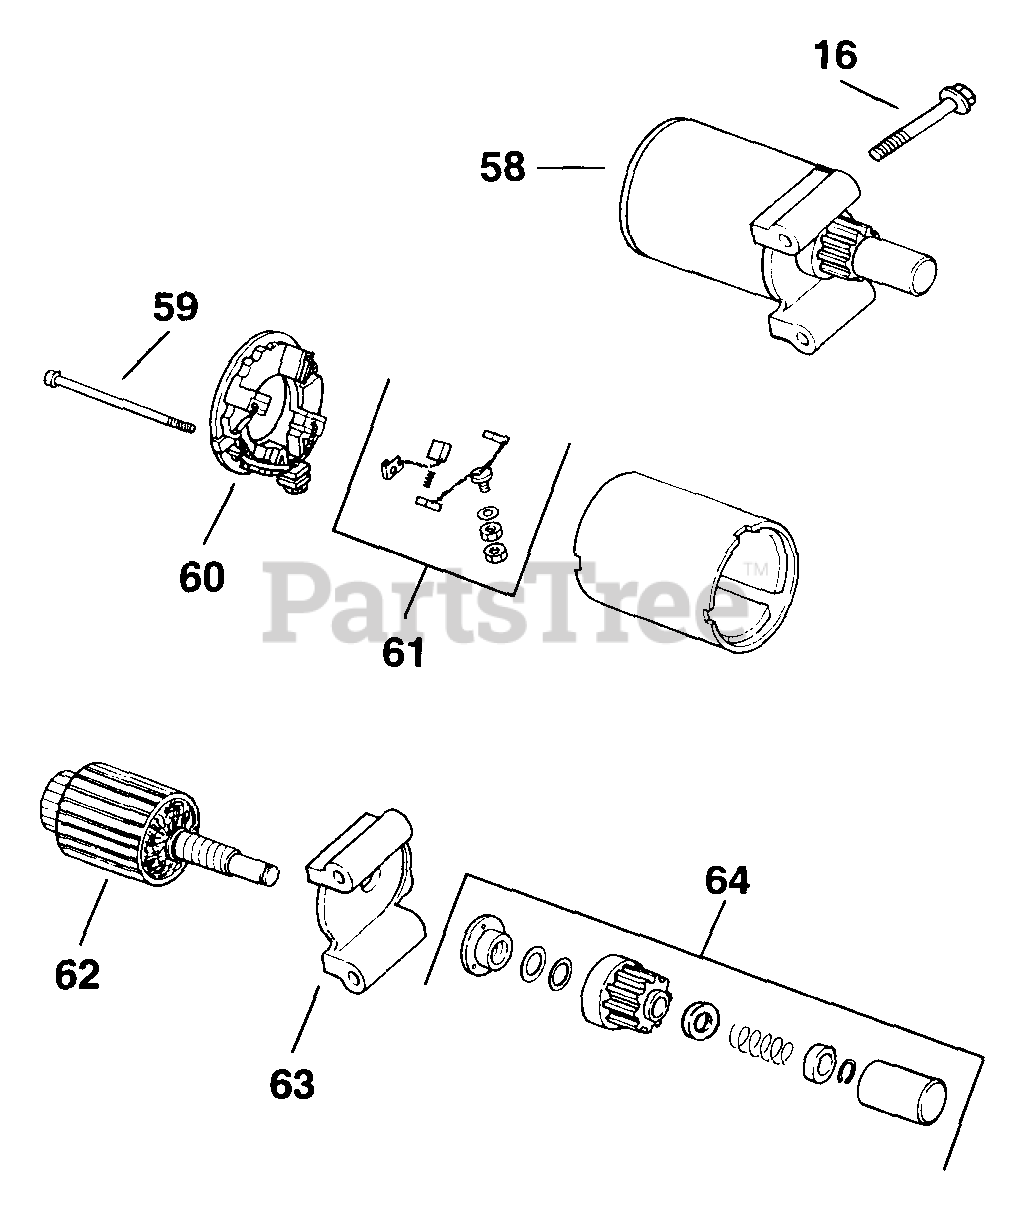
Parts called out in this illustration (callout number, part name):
59	SCREW - (#DSC)
60	COMMUTATOR, END CAP
61	KIT, BRUSH & SPRING - DISCONTINUED
62	ARMATURE ASSY - DISCONTINUED
64	KIT, DRIVE
